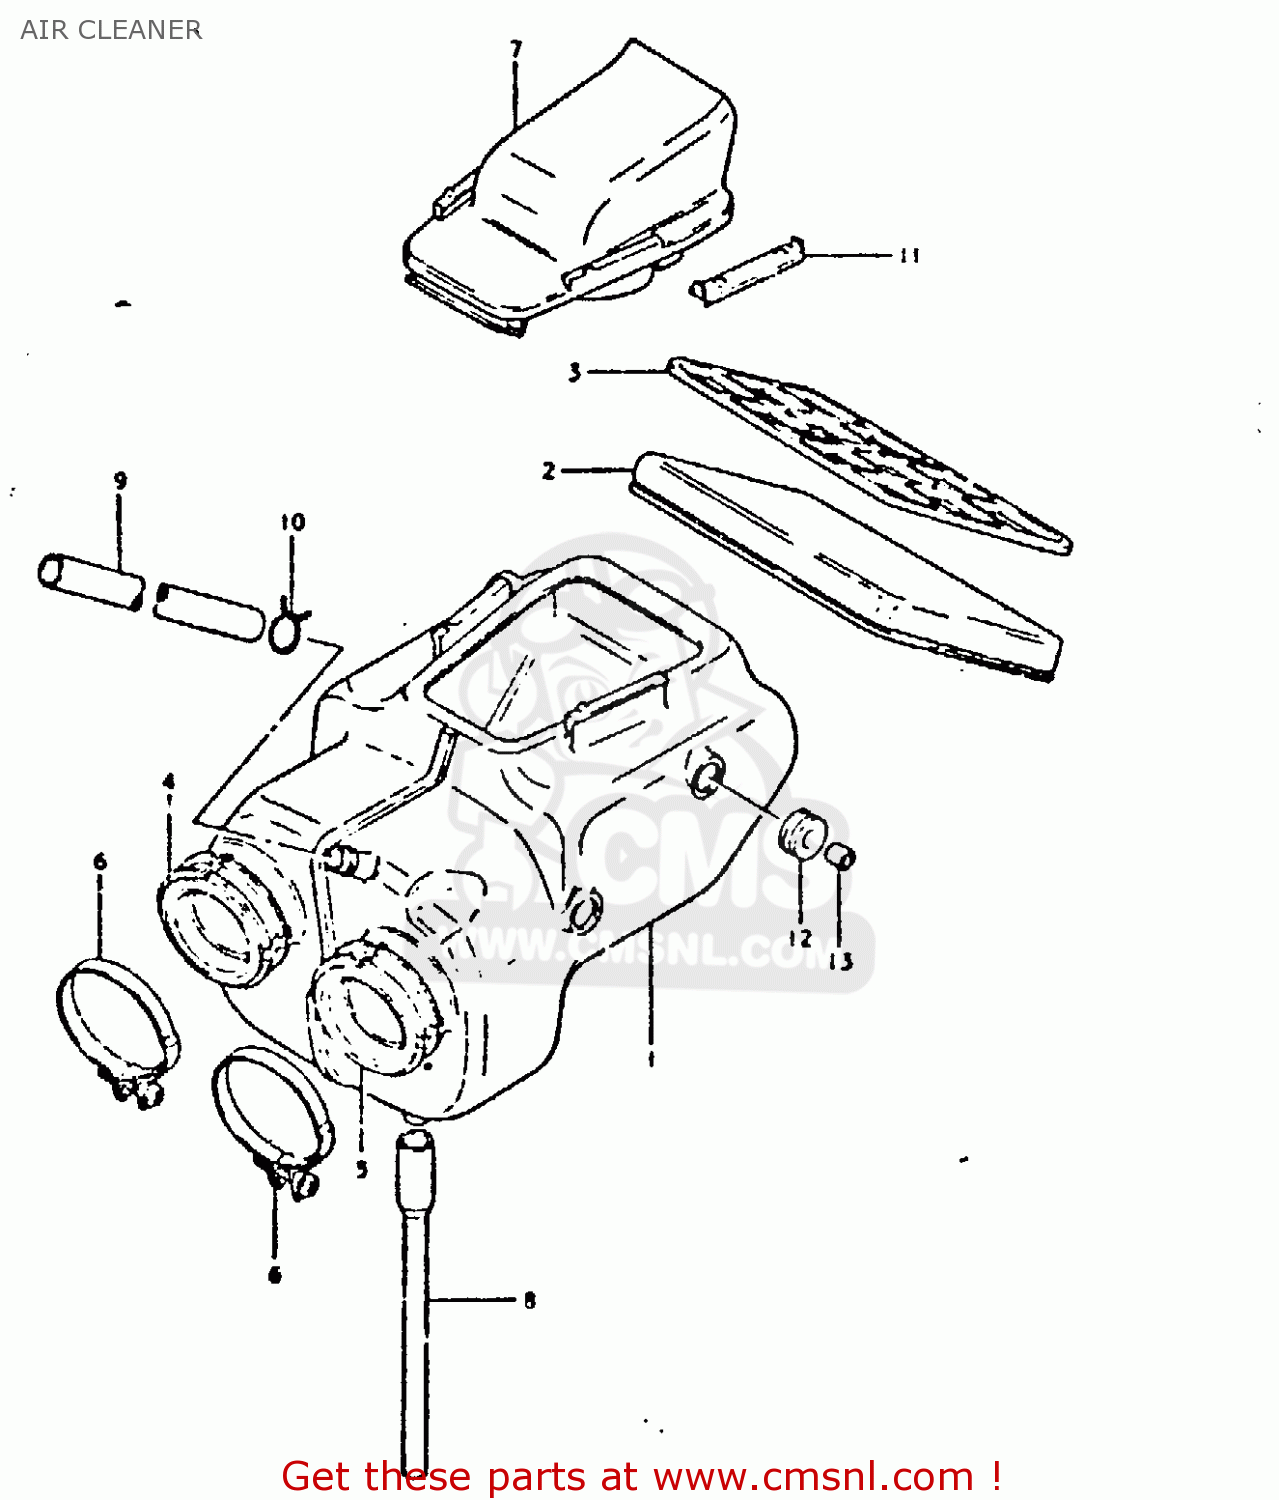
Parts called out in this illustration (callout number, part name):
1	CLEANER ASSEMBLY,AIR
2	FILTER
3	HOLDER NO.2
4	OUTLET,R
5	OUTLET,L
6	CLAMP
7	CAP
8	DRAIN TUBE
9	HOSE
10	CLAMP
11	SLIDER
12	CUSHION
13	SPACER(6.1X9X7.5)
